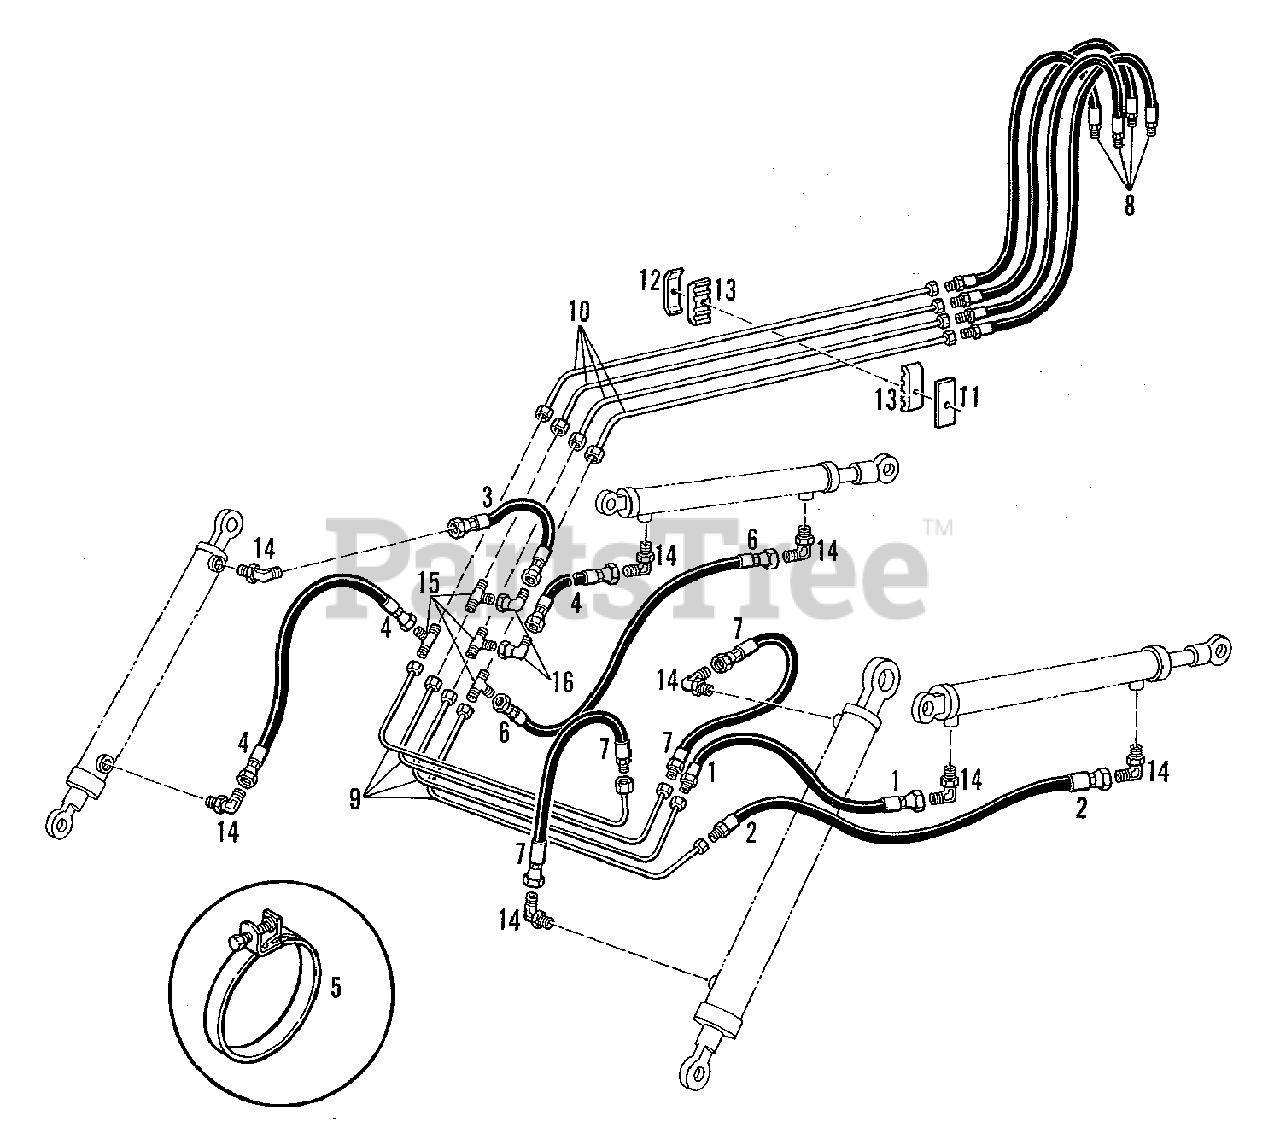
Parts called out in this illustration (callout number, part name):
1	HOSE ASSEMBLY (Left Lift Cylinder at Base End Position)
2	HOSE ASSEMBLY (Left Lift Cylinder at Rod End Position)
3	HOSE ASSEMBLY (Right Tilt Cylinder at Base End Position)
4	HOSE ASSEMBLY (Right Tilt Cylinder at Rod End Position & Right Lift Cylinder at Base End Position)
5	CLAMP, Hose (Attached to Lift Cylinder Barrel to Secure Hoses)
6	HOSE ASSEMBLY (Right Lift Cylinder at Rod End Position)
7	HOSE ASSEMBLY (Left Tilt Cylinder at Base & Rod Positions)
8	HOSE ASSEMBLY, Valve Operating
9	TUBE ASSEMBLY, Cross
10	TUBE ASSEMBLY, Side
11	CLAMP, Tube (Mounts on Studs Welded on Boom Assembly)
11	LOCKWASHER, 5/16
11	NUT, 5/16NC
12	BRACKET, Clamp
13	CUSHION, Clamp
14	ELBOW, Hose Adapter, 3/8 Tube O.D.
14	O-RING, 15/32 I.D.
15	TEE, 3/8 Tube O.D.
16	ELBOW, Swivel Adapter, 3/8 Tube O.D.
